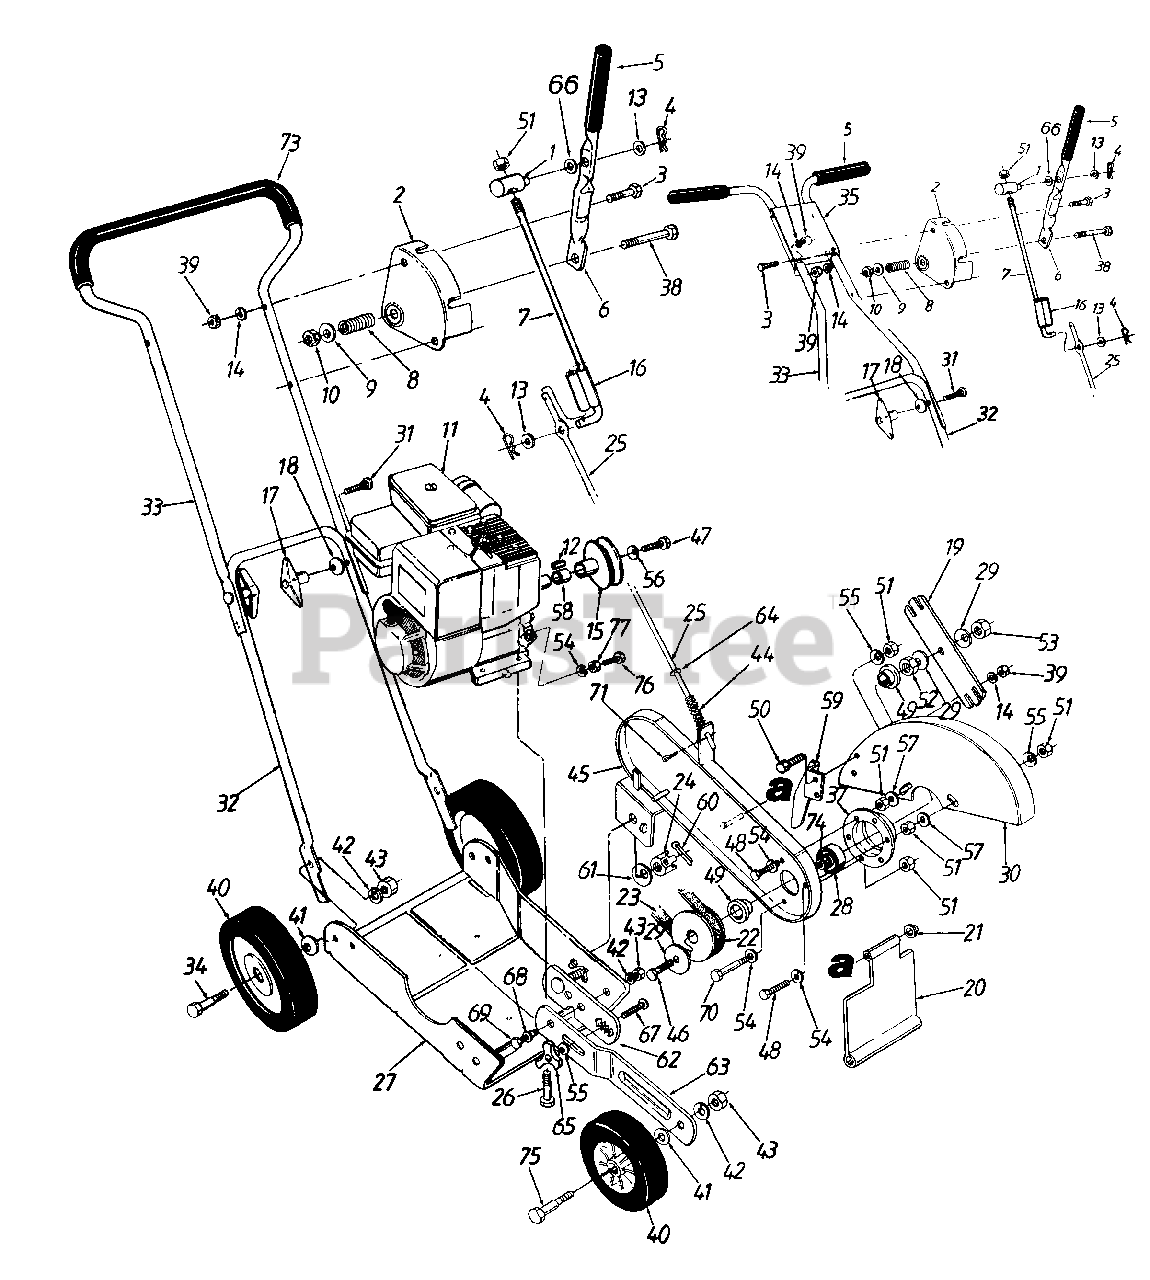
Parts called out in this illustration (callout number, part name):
1	Ferrule
4	Hairpin Clip
5	Foam Grip
7	Upper Clutch Rod
8	Compression Spring 1.38" Lg.
9	Fl-Wash .344" I.D.
10	Hex L-Nut 5/16-18 Thd.
11	Engine
12	Sq. Key 3/16" x 1" Lg.
13	Fl-Wash .344" I.D.
14	L-Wash. 1/4" I.D.
15	Engine Pulley
16	Clutch Rod Lock
17	Wing Nut Ass'y.
18	Saddle Wash .32" I.D. x .937" O.D.
20	Edger Guide Flap
21	Push Cap
22	3/8" "V"-Pulley
23	"V"-Belt
24	Hex Slotted Nut 1/2-20 Thd.
25	Lower Clutch Rod
26	Hex L-Wash. TT-Tap Scr. 3/8-16 x 1" Lg.
29	Bell-Wash. 5/8" I.D. x 1-1/4" O.D.
34	Shld. Bolt 3/8-16 Thd.
38	Hex Bolt 5/16-18 x 2" Lg.
39	Hex Nut 1/4-20 Thd.
40	Wheel Ass'y.
41	Bell-Wash .38" I.D. x .88" O.D.
42	L-Wash. 3/8" I.D.
43	Hex Nut 3/8-16 Thd.
44	Comp. Spring 2" Lg.
47	Hex Bolt 3/8-24 x 1.5" Lg. (Gr. 5)
48	Hex Cap Bolt 5/16-18 x 1-1/4" Lg.
49	Shld. Spacer .626" I.D.
50	Hex Bolt 1/4-20 x .5" Lg.
51	Hex Nut 5/16-18 Thd.
52	Hex Jam Nut 5/8-18 Thd.
53	Hex Ins. L-Nut 5/8-18 Thd.
54	L-Wash. 5/16" I.D.
55	Bell-Wash .345" I.D. x .88" O.D.
56	Bell-Wash .396" I.D. x .114" O.D.
57	Fl-Wash .312" I.D. x .75" O.D.
58	Spacer.748" I.D. x .985" O.D.
61	Bell-Wash .515" I.D. x 1.14" O.D.
65	Hand Knob
66	Spring Wash .32" I.D.
67	Carr. Bolt 5/16-18 x 1" Lg. (Special)
68	Spacer .383" l.D. x .503" O.D.
69	Hex Bolt 3/8-16 x 1" Lg.
70	Shld. Bolt 5/16-18 x 1.27" Lg.
71	Cotter Pin 1/8" Dia. x 1" Lg.
73	Foam Grip
74	Fl-Wash .64" I.D. x 1.12" O.D.
75	Shld. Bolt .498" Dia. x 1.64" Lg.
76	Hex Bolt 5/16-24 x 2.75" Lg. (Gr. 5)
77	Hex Nut 5/16-24 Thd.
